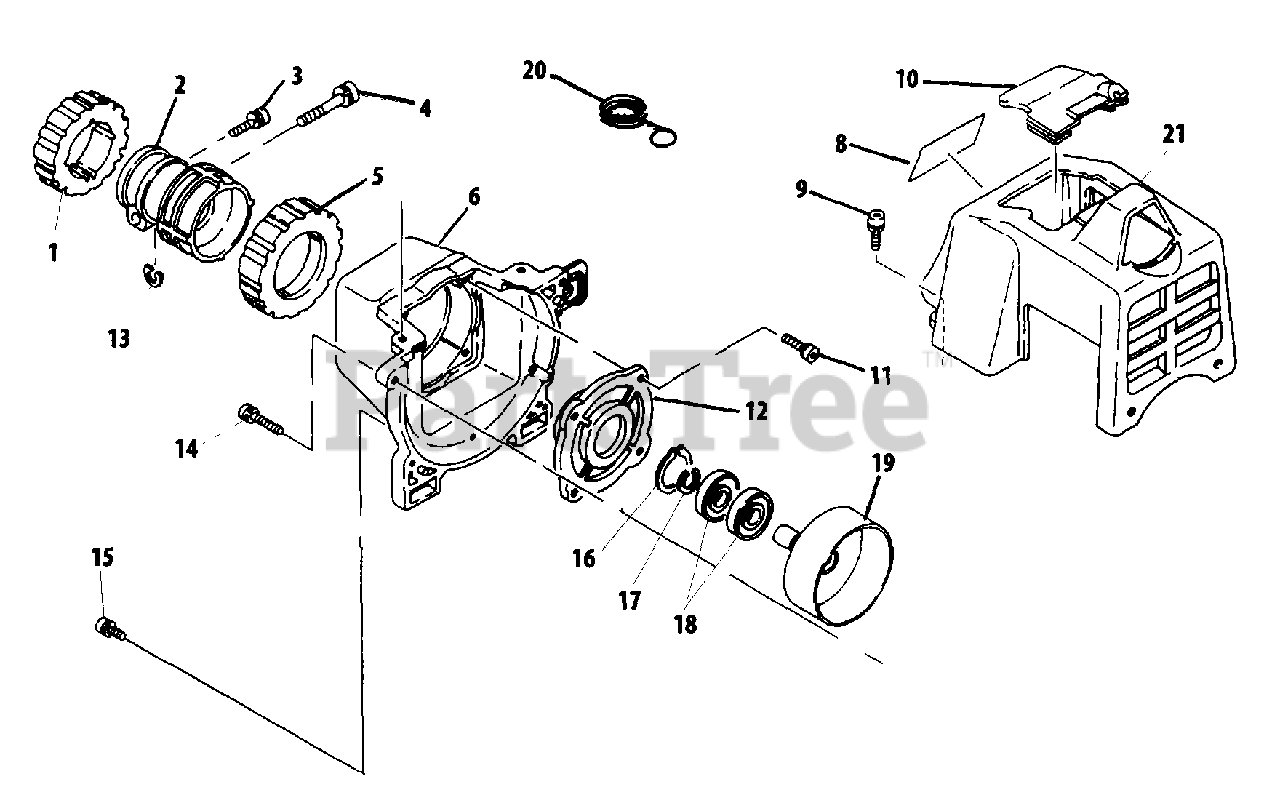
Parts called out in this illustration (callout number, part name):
1	CUSHION - FRONT
2	JOINT
3	SCREW - 5X16
4	SCREW - 6X28
5	CUSHION - REAR
6	CASE, FAN
8	LABEL - MODEL
9	SCREW - 5X16
10	COVER
11	SCREW - 5X16
12	CASE, CLUTCH
13	SHIM
14	SCREW - 5X18
15	SCREW - 5X20
16	RING, RETAINING - 28
17	RING, RETAINING
18	BEARING, BALL - 6001DDUC3
19	DRUM, CLUTCH
20	GUIDE, CABLE
21	COVER, ENGINE
